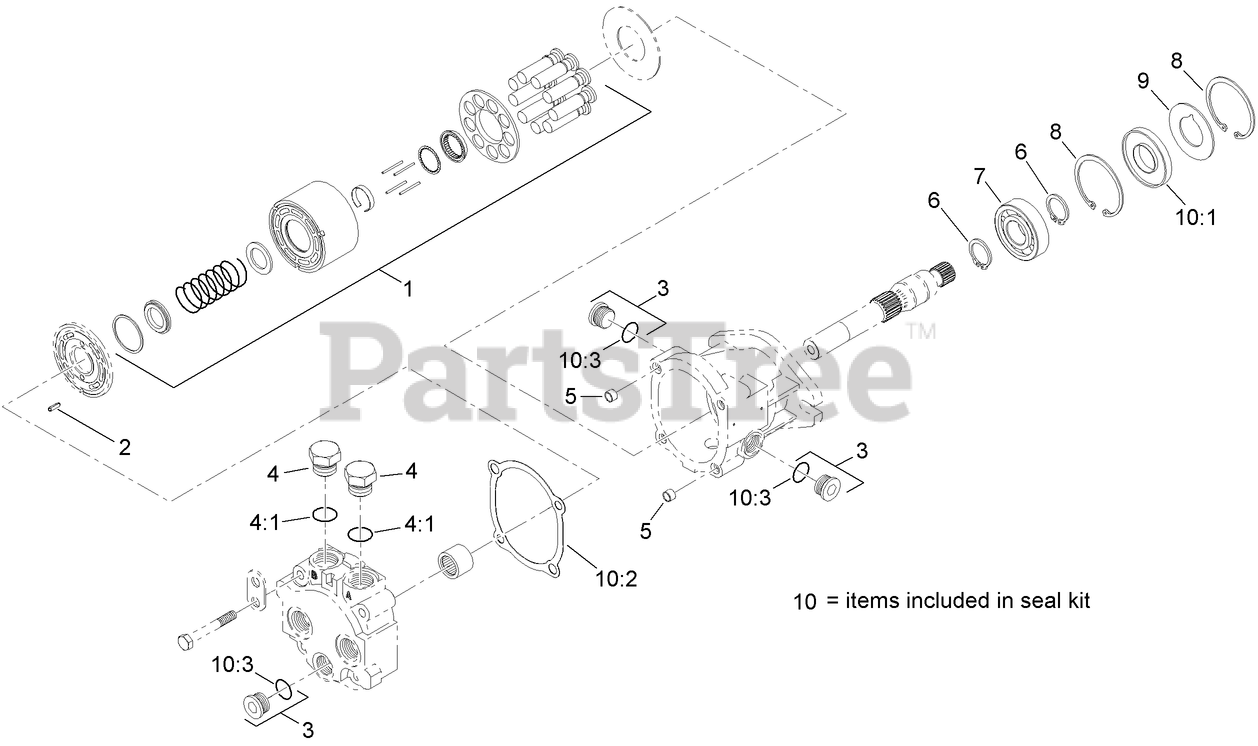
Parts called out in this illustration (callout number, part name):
1	CYLINDER BLOCK KIT
2	Pin-Spring
3	PLUG-PIPE
4:1	O-RING
5	PIN-SPRING
6	RING-RETAINING
7	BEARING-BALL
8	RING-RETAINING
9	WASHER-BACKUP
10	SEAL KIT
10:1	SEAL-LIP
10:2	Gasket-Cap, End
10:3	O-RING
